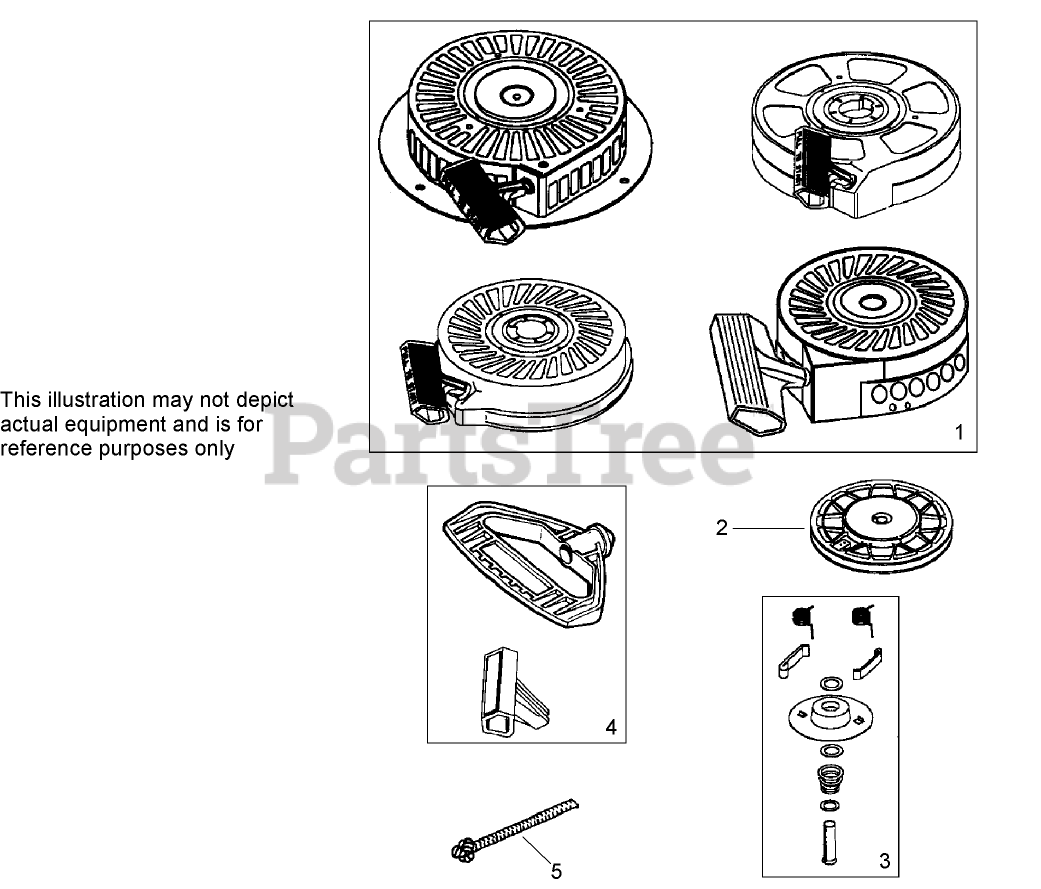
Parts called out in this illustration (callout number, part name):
1	Starter-Rewind
2	Pulley and Rewind Spring ASM
3	Repair Kit
4	Handle-Starter, Mitten Grip
5	Rope-Starter (98 cut to length)
